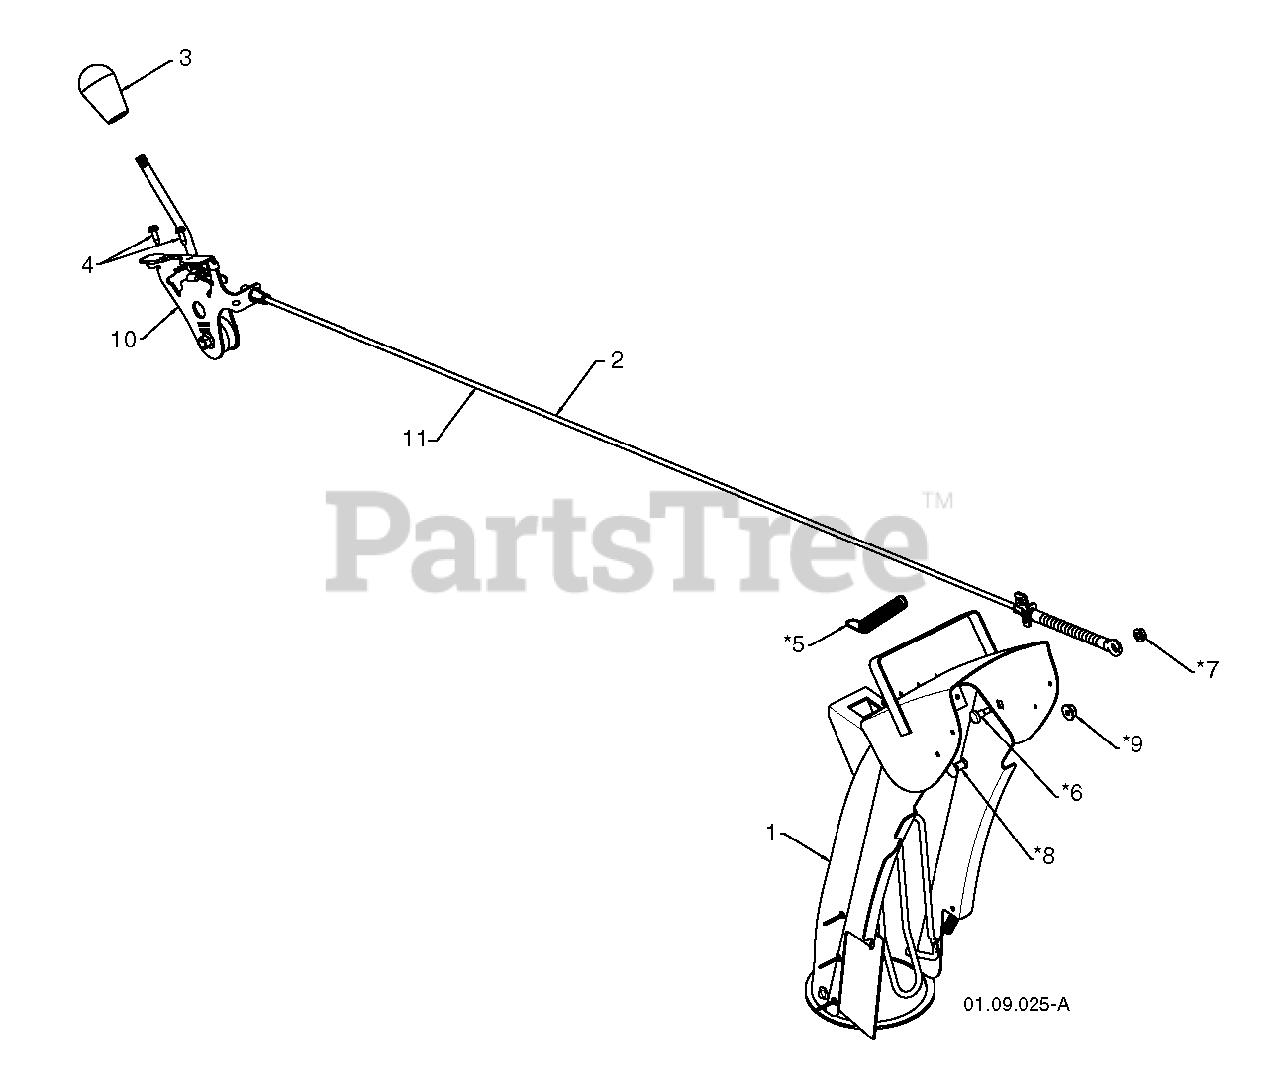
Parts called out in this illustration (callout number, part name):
2	CONTROL.ASM.DEFLECTOR
3	KNOB LEVER, BLACK
4	SCREW #10-24 X 5/8
6	BOLT, SHOULDER
7	NUT.HEX.FLANGE.1/4
8	BOLT
9	NUT, LOCK 5/16-18
10	CHUTE.DEFLECTOR.HEAD.SERVICE.
11	SERVICE.CHUTE.DEF.CBL.BLK
